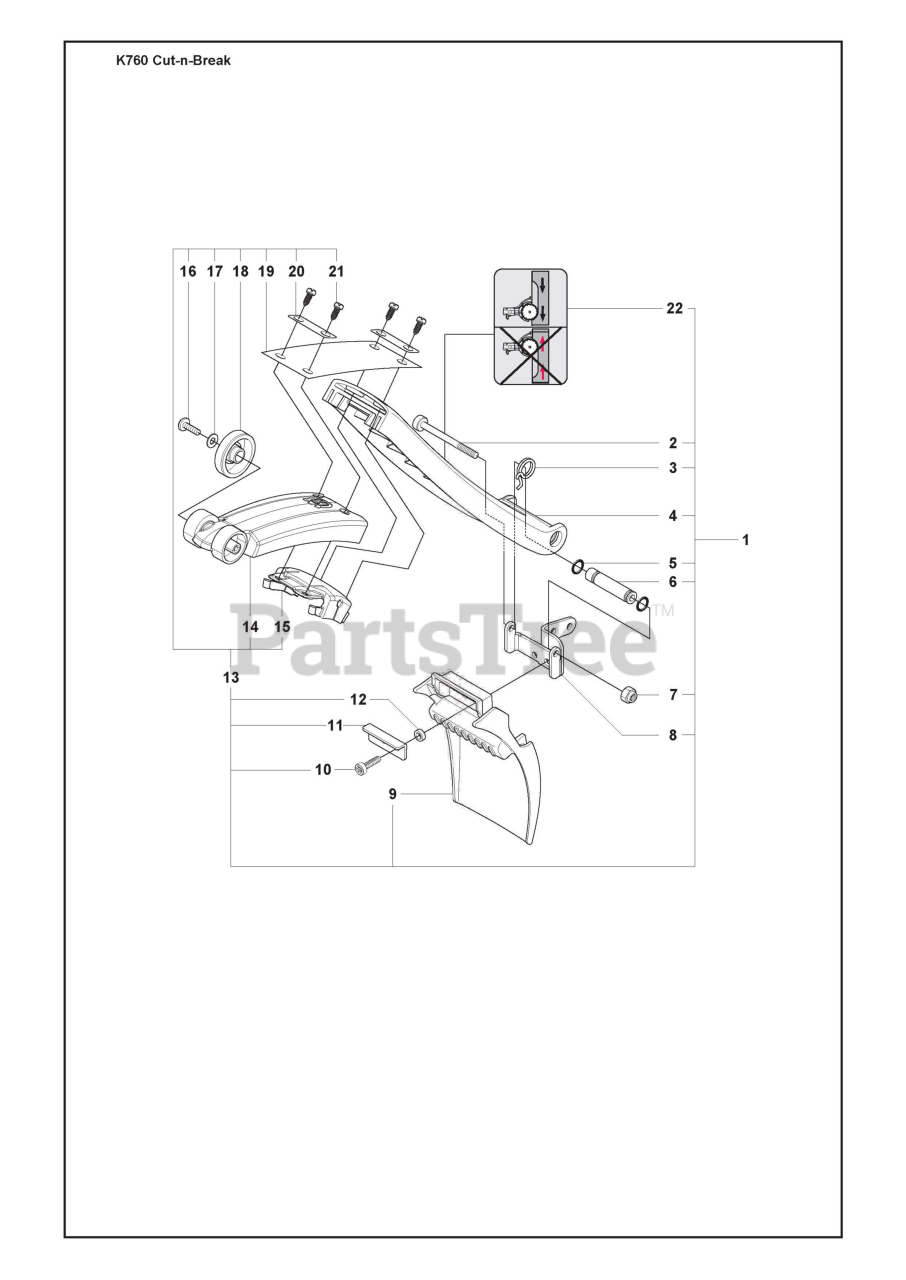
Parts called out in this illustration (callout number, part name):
1	Spray Guard Assy
4	Spray Guard
9	Spray Guard
13	Spray Guard Assy
14	Spray Guard Upper
15	Guide Piece
